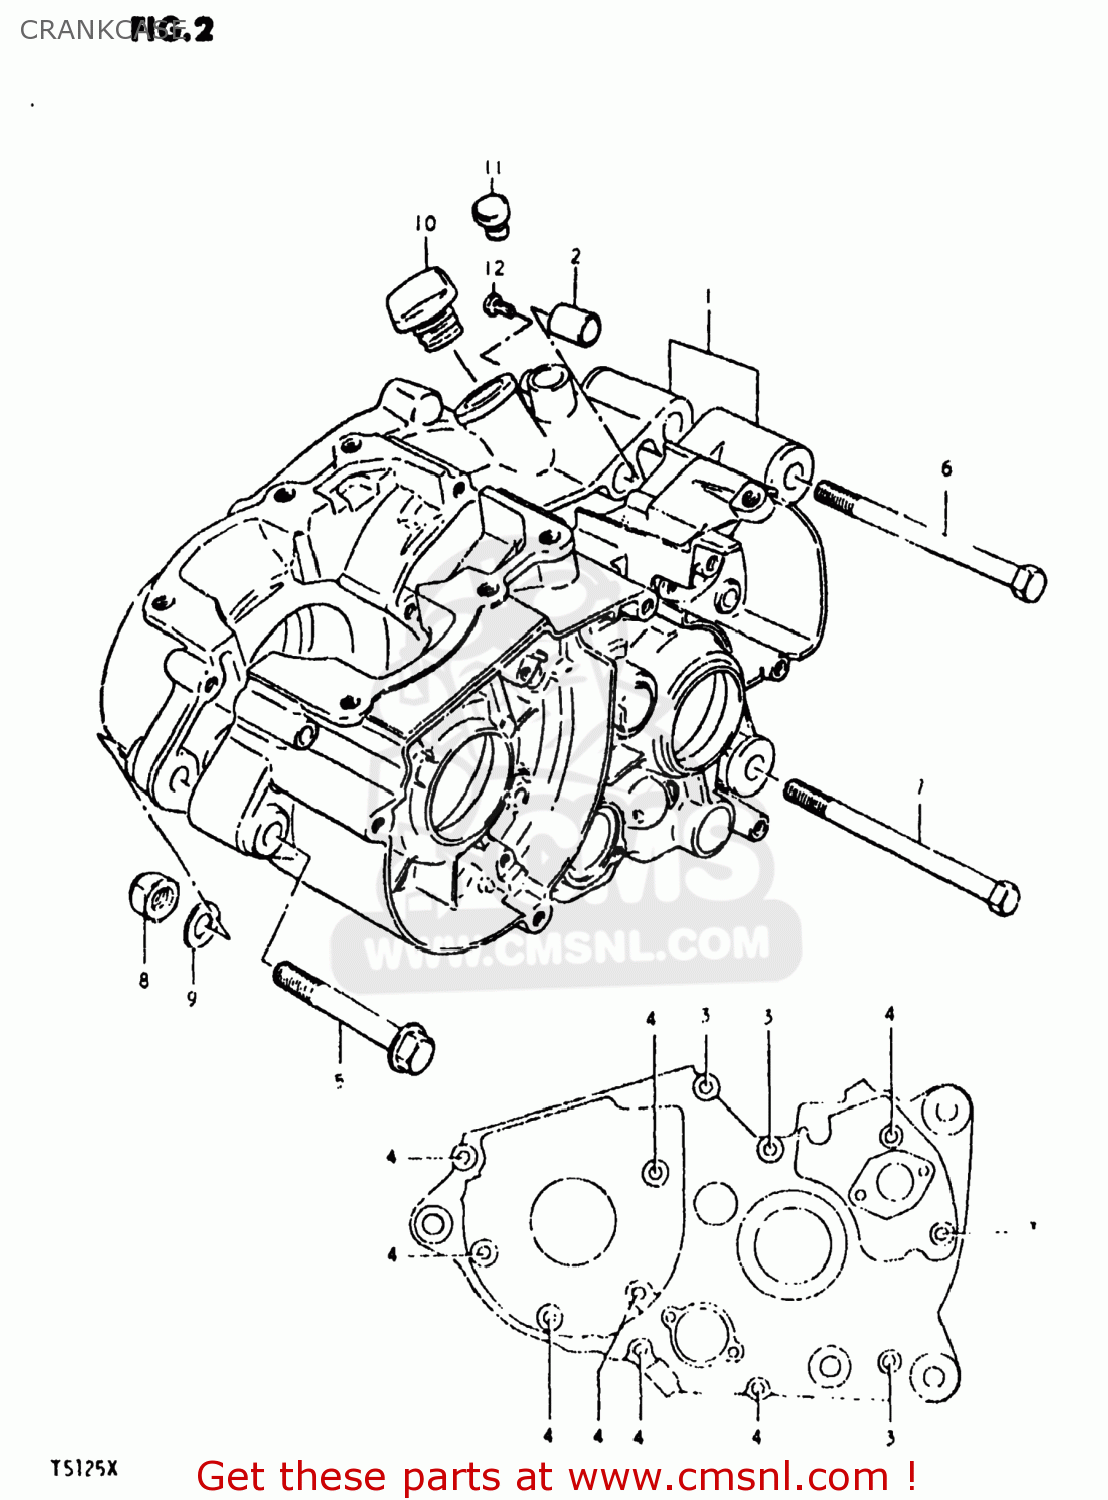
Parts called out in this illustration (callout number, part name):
1	CRANKCASE ASSEMBLY
2	PIN
3	SCREW
4	SCREW 6X60
5	BOLT (10X75)
6	BOLT(10X110)
7	BOLT
8	NUT
9	WASHER
10	PLUG
11	Plug
12	SCREW,6X6
